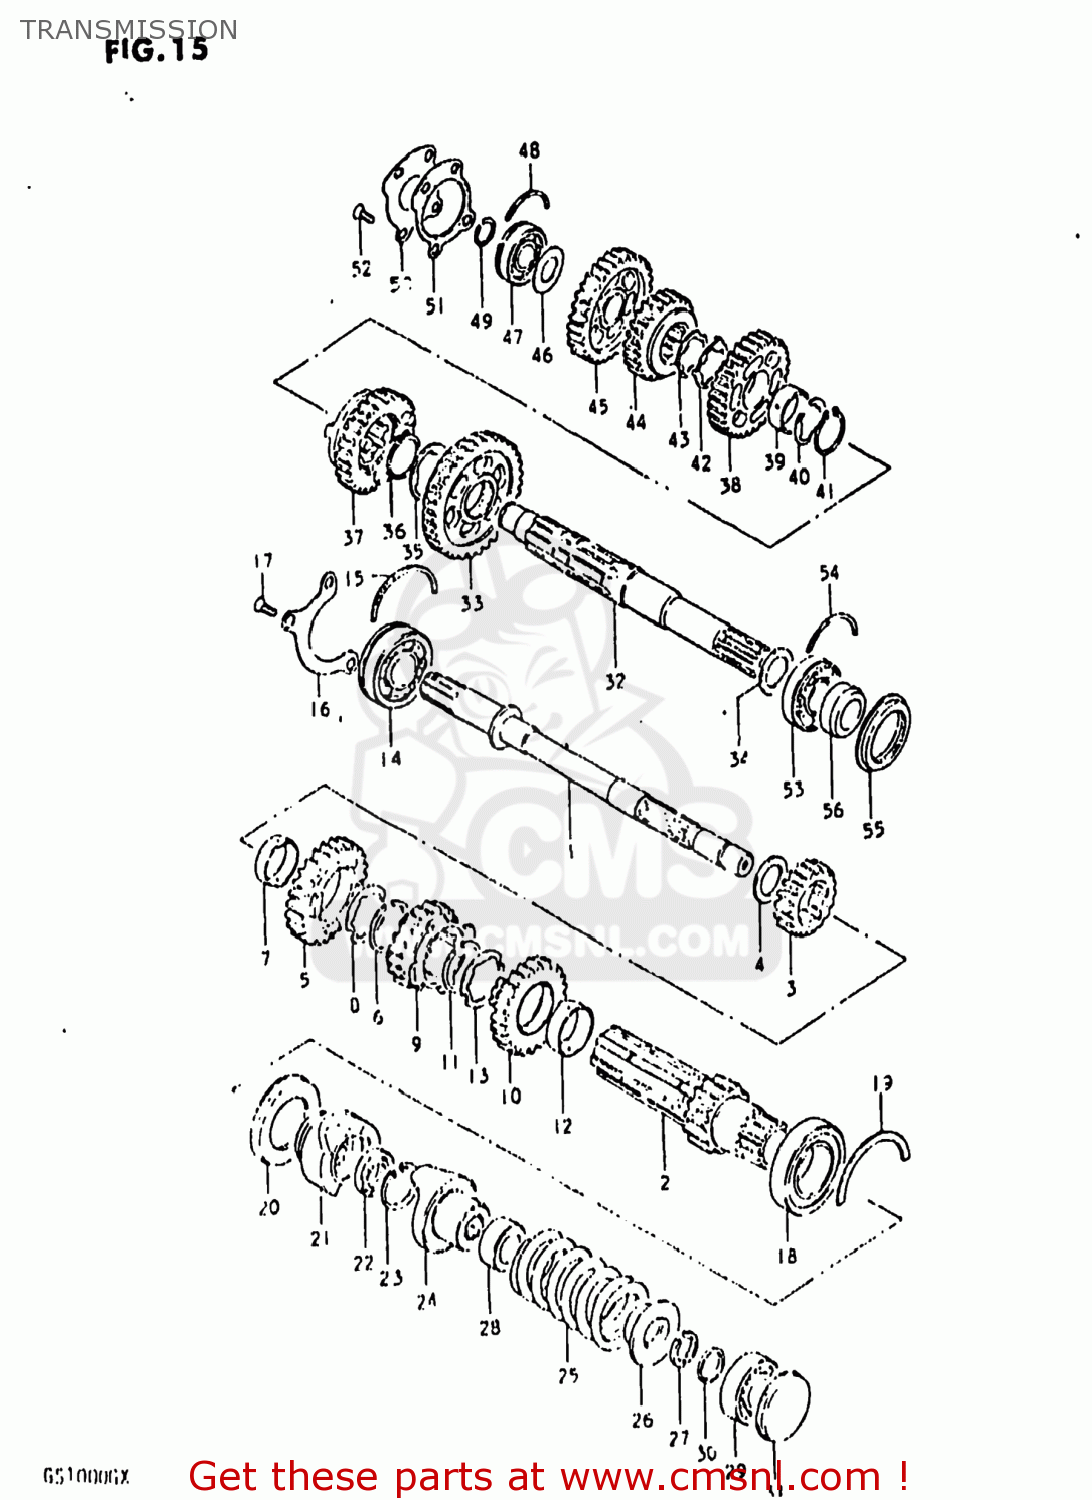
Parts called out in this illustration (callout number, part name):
1	SHAFT,COUNTER
2	SHAFT,OUTER COUNTER
3	GEAR,SECOND DRIVE
4	WASHER (21X35X2)
5	GEAR,5TH DRIVE(NT:26)
6	RING,SNAP
7	SPACER,DRIVE GEAR
8	LOCK WASHER,5TH DR GEAR SPACER
9	GEAR,THIRD DRIVE
10	GEAR,FOURTH DRIVE
11	RING,SNAP
12	SPACER,DRIVE GEAR
13	LOCK WASHER,5TH DR GEAR SPACER
14	BEARING(25X62X17)
15	C-RING
16	RETAINER,CNTR SHAFT BEARING
17	SCREW
18	BALL BEARING 32X58X13
19	C-RING
20	SEAL,OIL(40X58X7)
21	DOG,OUTPUT CAM
22	SEAL,OIL(20.6X31X6)
23	CIRCLIP
24	DOG,INPUT CAM
25	SPRING
26	STOPPER,CAM DOG
27	STOPPER,CAM DOG
28	GUIDE,CAM DOG SPRING
29	BEARING
30	SPACER (17X21X3.5)
31	PLUG
32	SHAFT,DRIVE
33	GEAR,FIRST DRIVEN
34	WASHER, LH
35	WASHER,LOCK
36	CIRCLIP
37	GEAR,FOURTH DRIVEN
38	GEAR,THIRD DRIVEN
39	BUSH,3RD DRIVEN GEAR
40	WASHER,LOCK
41	CIRCLIP
42	WASHER
43	WASHER,LOCK
44	GEAR,FIFTH DRIVEN
45	GEAR,SECOND DRIVEN
46	WASHER
47	BEARING(20X47X14)
48	C RING
49	CIRCLIP
50	PLATE,DRIVESHAFT
51	GASKET,DRIVESHAFT PLATE (MCA)
52	SCREW
53	BEARING
54	C RING
55	SEAL,OIL(35X52X6)
56	SPACER,DRIVESHAFT,LEFT
